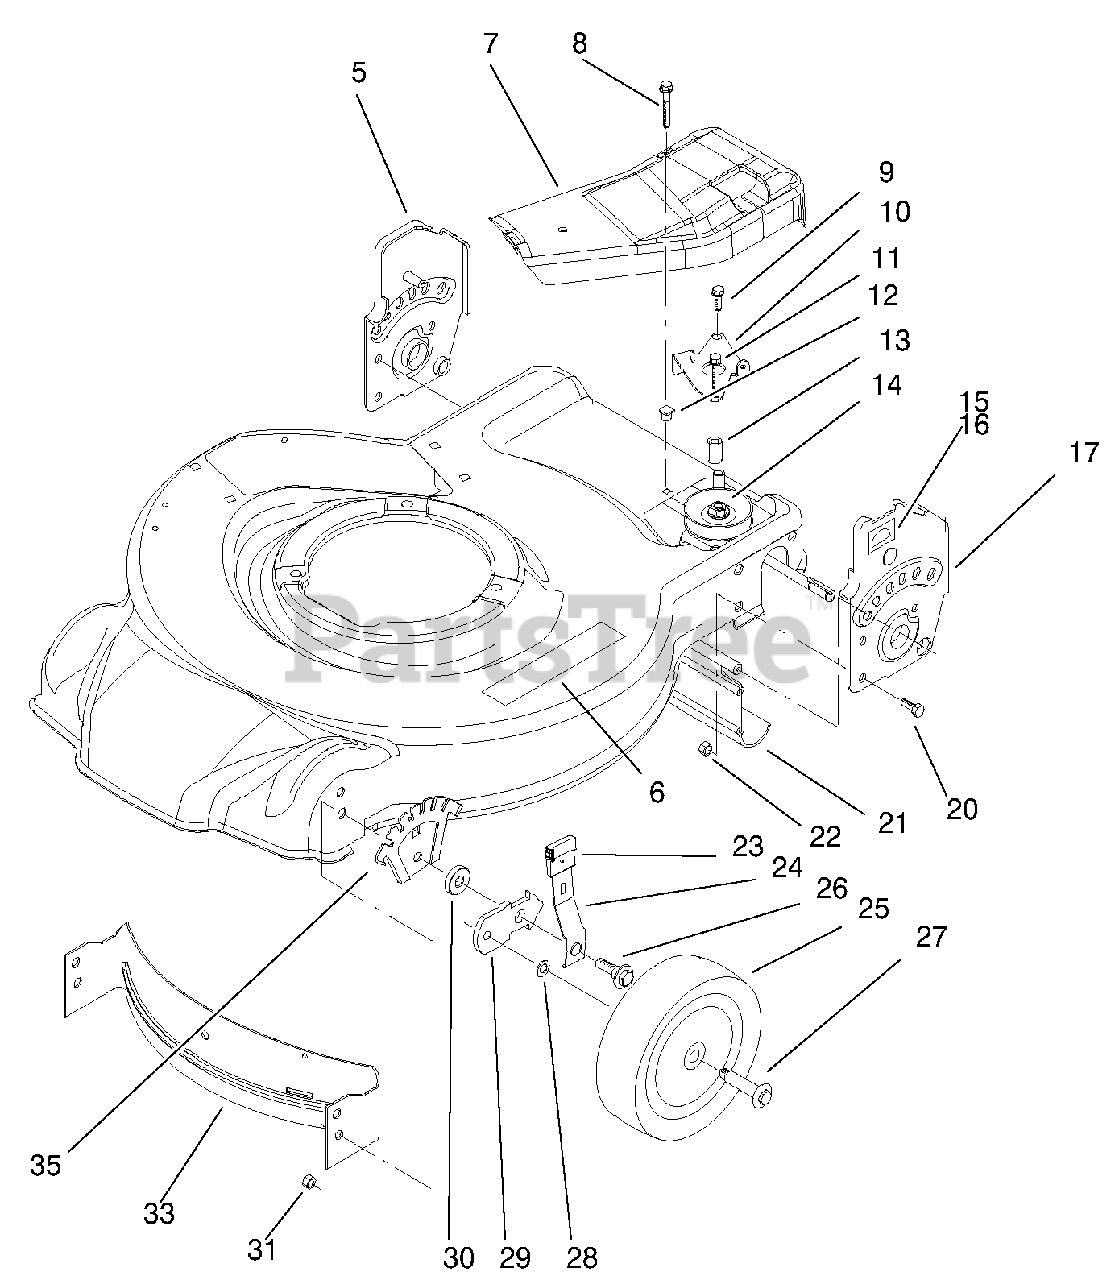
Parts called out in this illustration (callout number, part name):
5	ASM-RH Handle Bracket
6	Decal-Danger
7	Cover-Transmission
8	Screw-Pth
9	Screw-Tapping
10	Guide-Transmission
11	Screw-HWHTF
12	Grommet
13	Bushing-Plate, Actuator
14	Gear Case ASM
15	Decal-HOC
16	Decal-HOC
17	ASM-LH Handle Bracket
20	Screw-HH
21	Shield-Trailing
22	Nut-Lock
23	Knob-Lever, Height Adjustment
24	Arm-Front Spring
25	Wheel ASM
26	Bolt-Shoulder
27	Bolt-Shoulder
29	Bracket-Height Adjustment, Wheel
30	Washer-Wheel
31	Nut-Lock, NI
33	Baffle-Front
35	Plate-Height Adjustment
